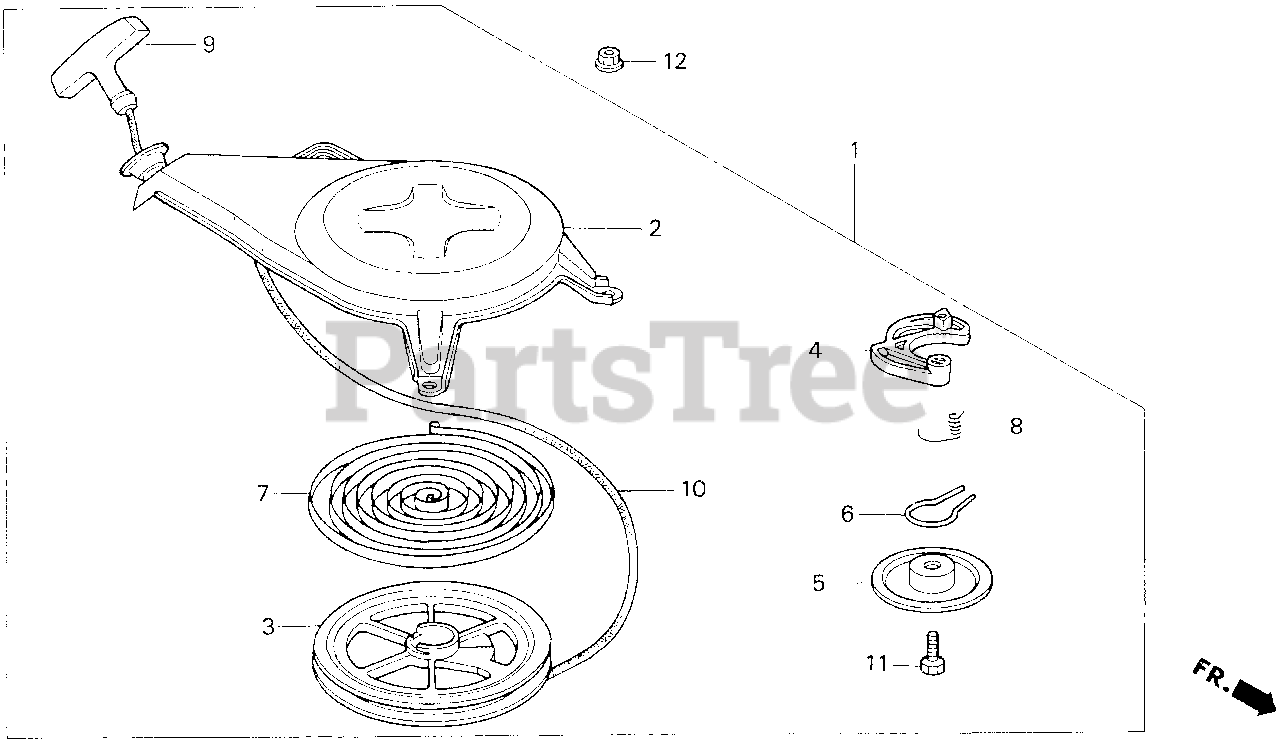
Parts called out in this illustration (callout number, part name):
1	STARTER ASSY., RECOIL
2	CASE, RECOIL STARTER
3	REEL, RECOIL STARTER
4	RATCHET, STARTER
5	PLATE, FRICTION
6	SPRING, FRICTION
7	SPRING, RECOIL STARTER
8	SPRING, RETURN
9	KNOB, STARTER
10	ROPE, RECOIL STARTER (#4X65") (N/A: USE ALTERNATE P/N 08540-ZG921-11)
11	BOLT, HEX. (6X20)
12	NUT, FLANGE (5MM)
